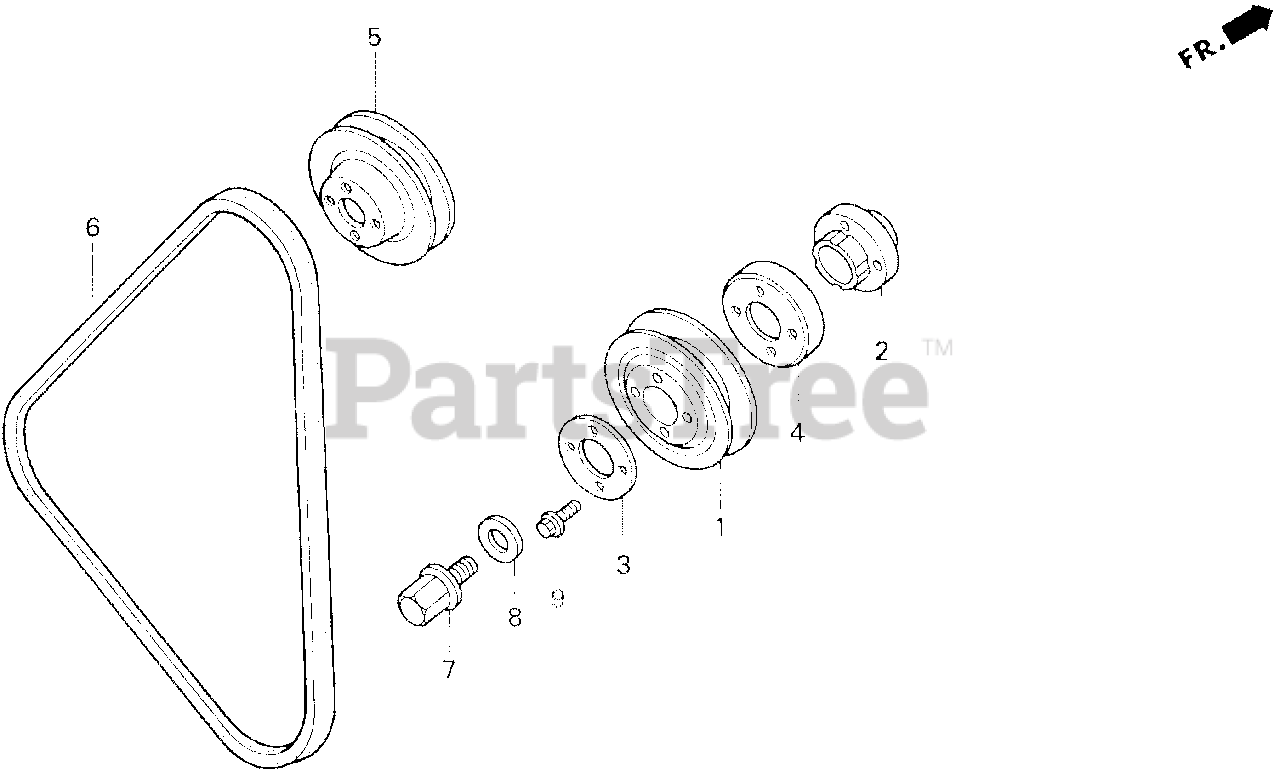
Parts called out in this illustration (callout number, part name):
1	PULLEY, CRANKSHAFT (118MM)
2	BOSS, CRANK PULLEY
3	SPACER, CRANK PULLEY
4	PLATE, CRANKSHAFT PULLEY
5	PULLEY, WATER PUMP
6	BELT, ALTERNATOR (BANDO)
7	BOLT, SPECIAL (12MM) (SAGA)
8	WASHER (12X30X4.5)
9	BOLT, FLANGE (6X16)
